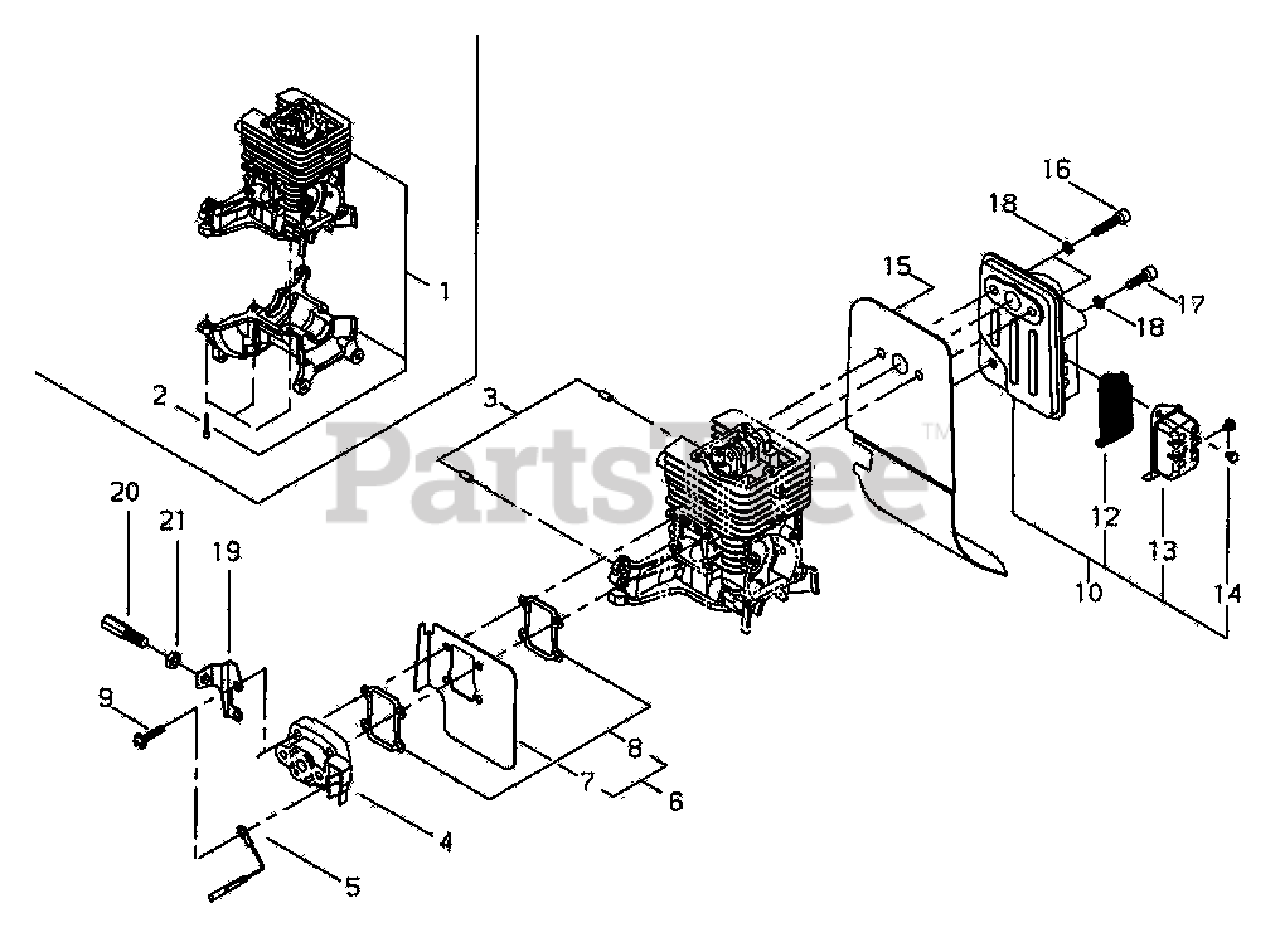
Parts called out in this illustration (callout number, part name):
1	CYLINDER & CRANKCASE ASSY
2	BOLT 5×16
3	PIN, LOCATING Ø4×8
4	INSULATOR WITH REED VALVE
5	LEAD - GROUND L= 110 MM
6	SHIELD ASSY, INTAKE HEAT
7	HEAT SHIELD, INTAKE
8	GASKET, EXHAUST
9	SCREW M5×22
10	MUFFLER ASSY
12	SCREEN, SPARK ARRESTER
13	GUIDE, EXHAUST
14	SCREW M4×6
15	HEAT SHIELD, EXHAUST
16	BOLT M5×25
17	BOLT 5×16
18	WASHER, FLAT 5.5×10×0.8
19	BRACKET, THROTTLE CABLE
20	ADJUSTER, THROTTLE CABLE
21	NUT, ADJUSTER LOCK M6
